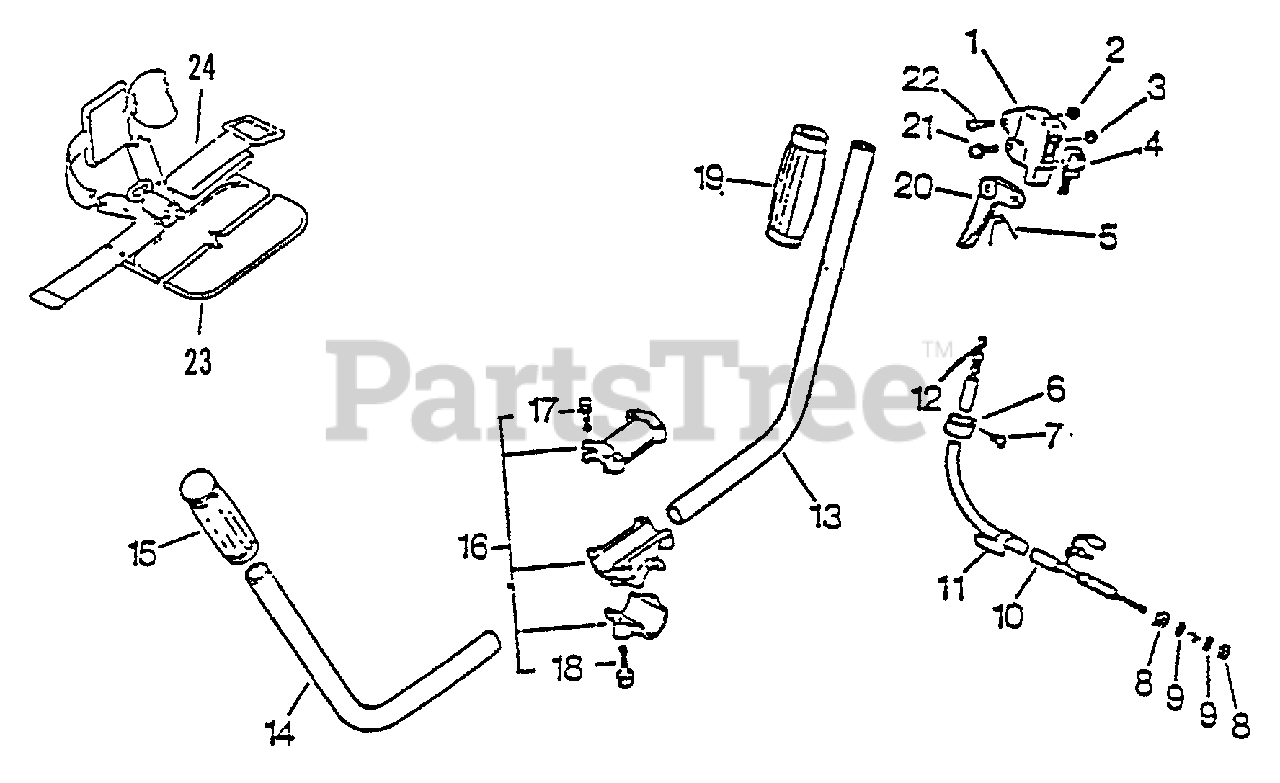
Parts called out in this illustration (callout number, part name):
1	BRACKET, THROTTLE
2	NUT, LOCK M5
3	NUT M5
4	SWITCH, ON-OFF
7	SCREW 5×10
9	WASHER 6.5×11.5×0.8
12	CABLE, THROTTLE
14	HANDLE, LEFT
15	GRIP, HANDLE
16	HANDLE BRACKET KIT
17	BOLT - 5×25
18	BOLT - 6×30
20	TRIGGER, THROTTLE
21	SCREW 5×25
23	PAD, HIP
24	SHOULDER STRAP ASSY
